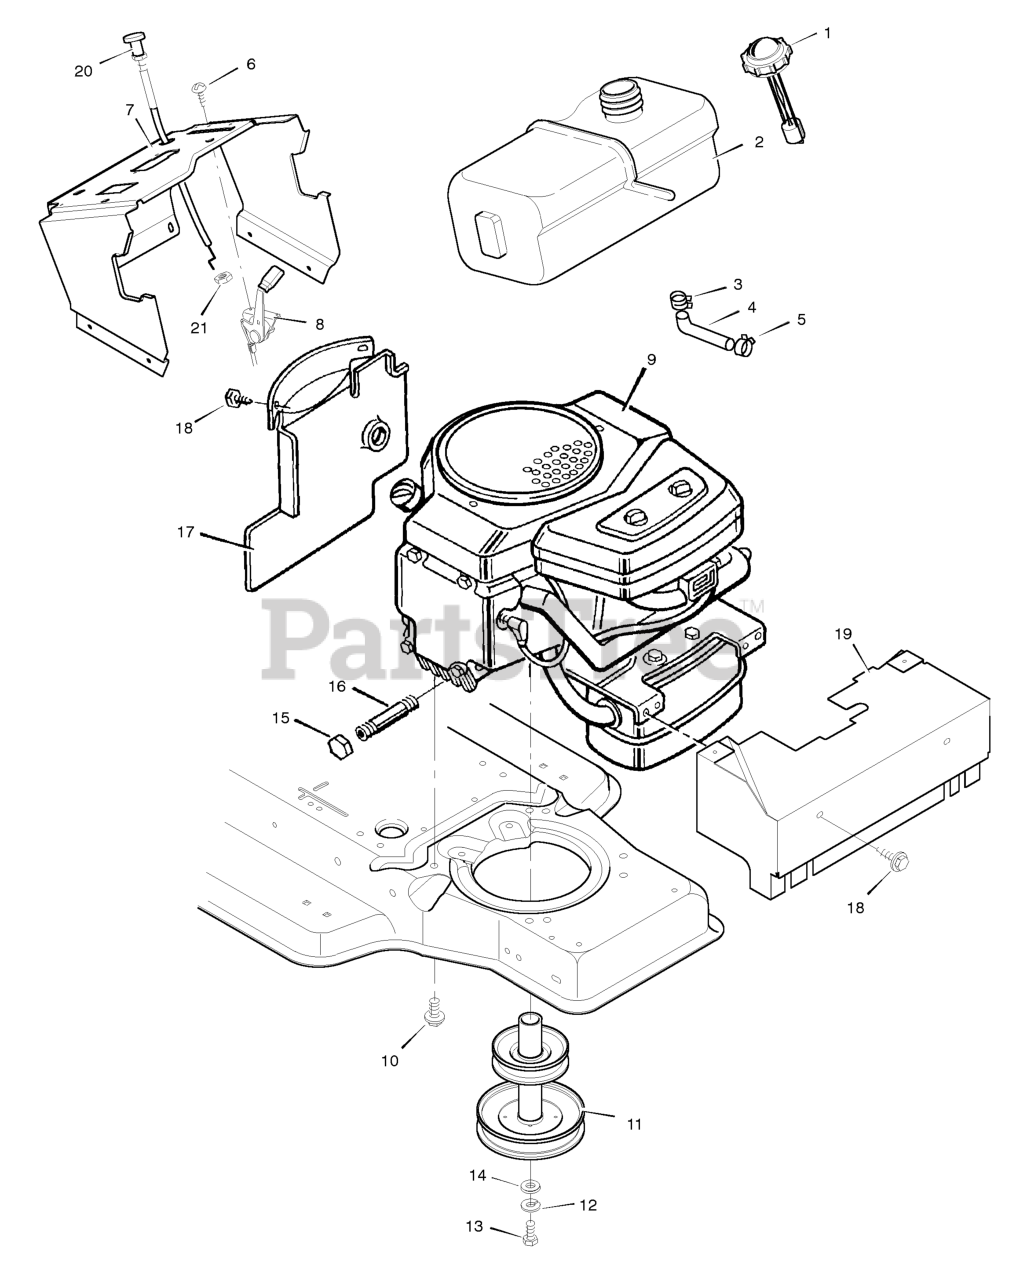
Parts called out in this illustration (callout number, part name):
1	Fuel Cap
2	Fuel Tank
3	Hose Clamp
4	Fuel Line
5	Hose Clamp
7	Support, Dash
8	Throttle Control
9	Engine *
10	Bolt, Engine Mount
11	Stack Pulley Assembly
12	Lockwasher
13	Bolt, Hex
15	Cap, Oil Drain
16	Pipe, Oil Drain
17	Baffle, Rear Engine
18	Screw
19	Baffle, Front Engine
21	Washer
